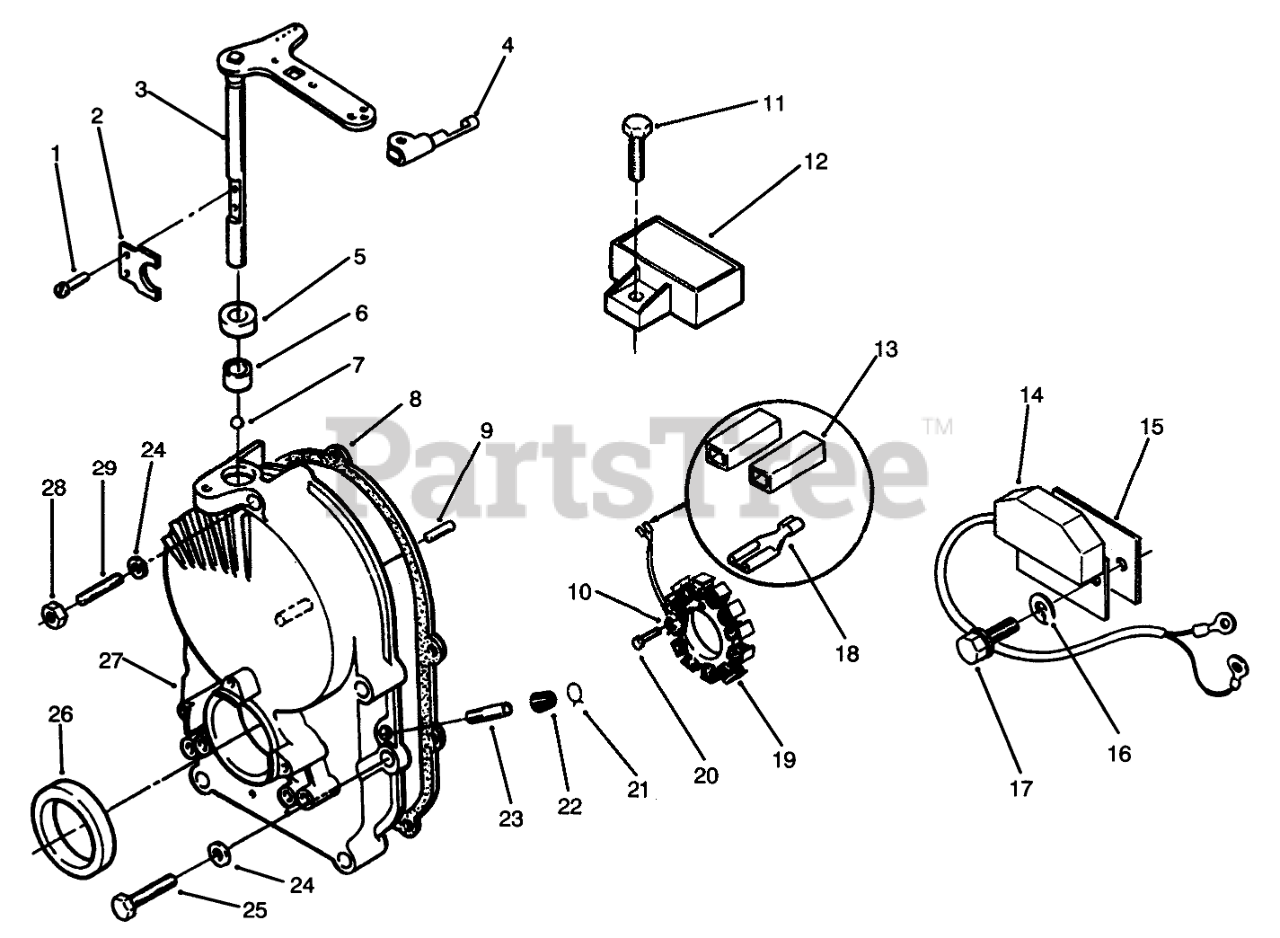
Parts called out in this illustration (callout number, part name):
1	SCREW-PAN HD
3	SHAFT AND ARM
6	BEARING
8	Gasket
9	PIN-DOWEL
10	WASHER-LOCK
11	SCREW-HWH
12	REGULATOR
13	Body-Terminal Conn. Kit (Incl. Ref. #18)
14	CONTROL-IGNITION
15	Insulator
16	WASHER-LOCK
17	Bolt
18	TERMINAL
19	Stator (Incl. Ref. #18)
20	Screw-HH
21	CLAMP
22	CAP-FUEL OUTLET
23	TUBE-PORT, VACUUM
24	WASHER
25	HEX-HEAD CAP SCREW
27	Kit-Gearcase (Incl. Ref. #1-3, 5-7, 9, 21-23 & 26)
28	NUT-GEAR COVER
29	STUD-GEAR COVER
